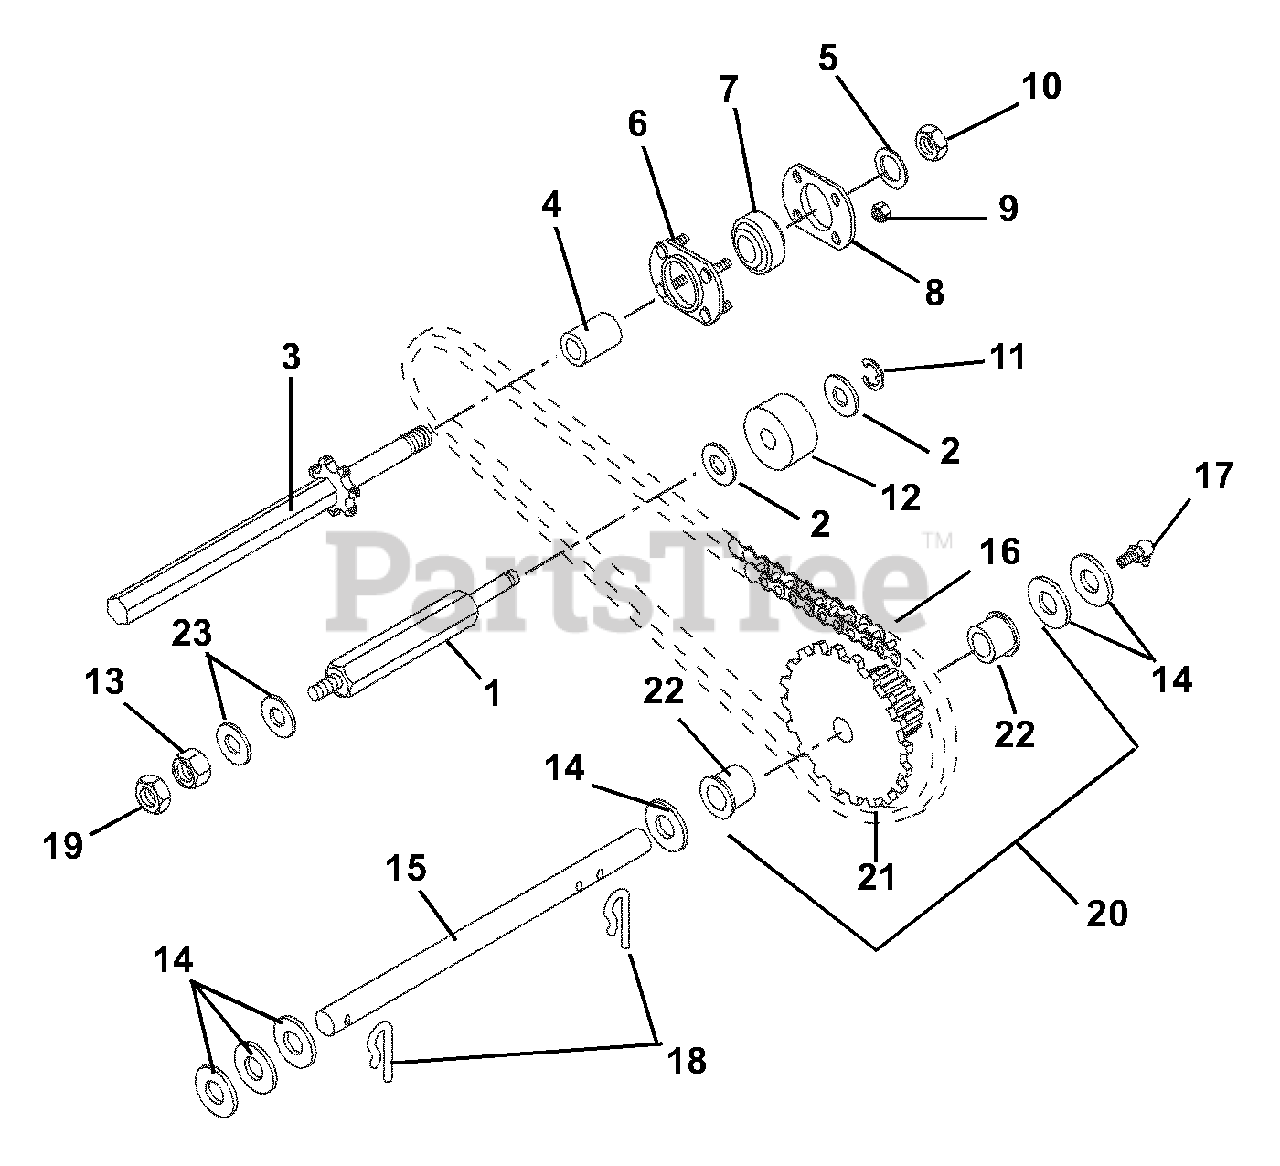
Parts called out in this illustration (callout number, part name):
1	Hex Shaft
2	Washer, Flat Steel .34 x .69 x .065
3	Shaft, Hex with Sprocket
4	Spacer .45 x .75 x 1.60
5	Washer, Flat Steel .51 x .88 x .072
6	Bearing Flange
7	Bearing, Ball .44 x 1.38 x .44
8	Bearing Flange
9	Nut, Locking Dual Face 10-24
10	Nut, Locking Center .44-14
11	Ring, Retaining External .31 x .025
13	Nut, Locking Center .31-18
14	Washer, Flat Steel .630 x 1.01 x .062
15	Shaft, Pinion
16	Roller Chain #41-34 Pitches
17	Fitting, Hydraulic Drive
18	Pin, Spring Clip
19	Nut, Jam .31-18
20	Pinion and Sprocket Assembly
21	Pinion and Sprocket
22	Bushing, Flange .63 x .75 x .50 x .88
23	Washer, Flat Steel .38 x .88 x .083
